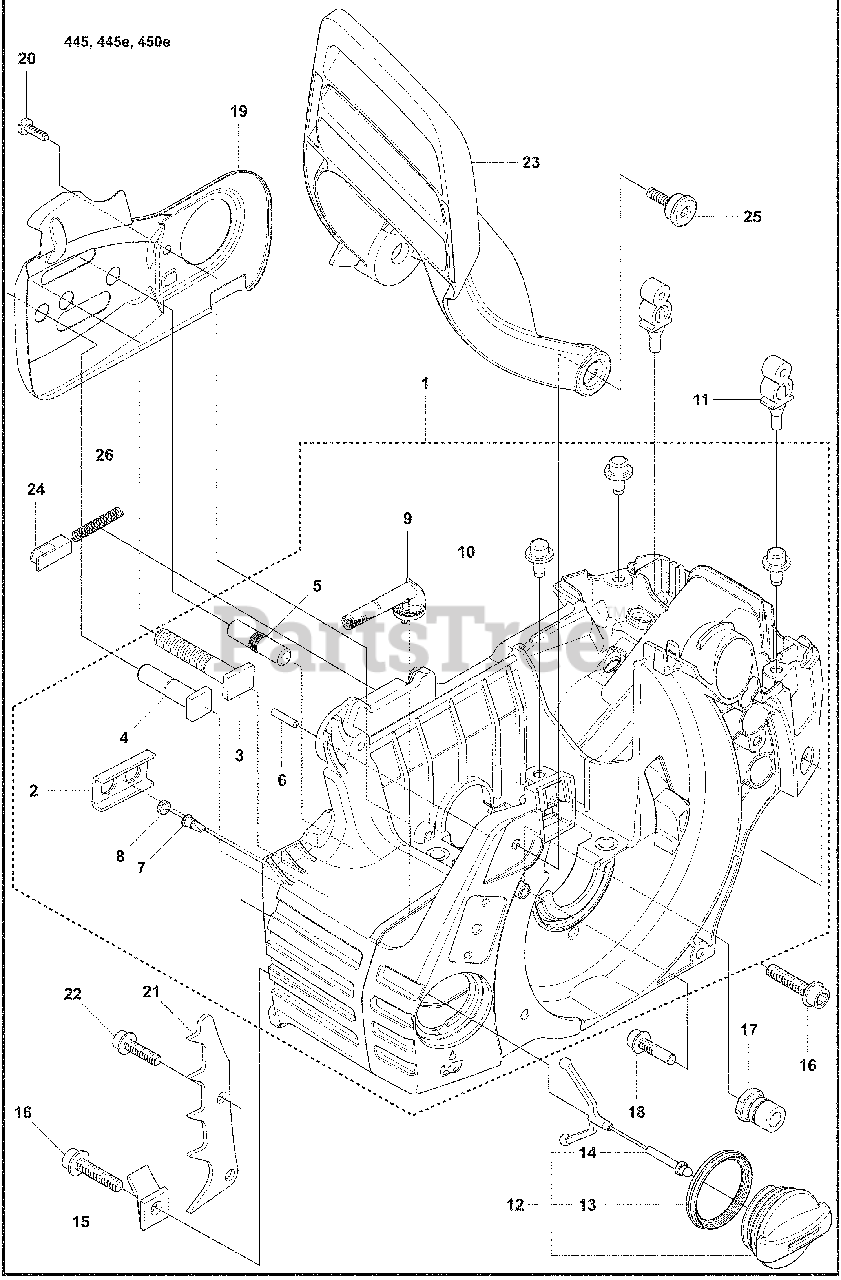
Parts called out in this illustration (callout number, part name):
2	Stiffening Plate
4	Bar Bolt, X2
7	Valve Check, Duckbill
8	Sintered Filter, Bronze
9	Oil Screen
12	Fuel Tank Cap Assembly, Grey
13	Sealing Gasket
15	Chain Catcher
16	Screw, 3 X 25 IHSCFT
17	Lateral Support
18	Screw, Ihscft
19	Chain Guide Plate
21	Felling Dog
23	Hand Guard
25	Screw
26	Lock Spring
